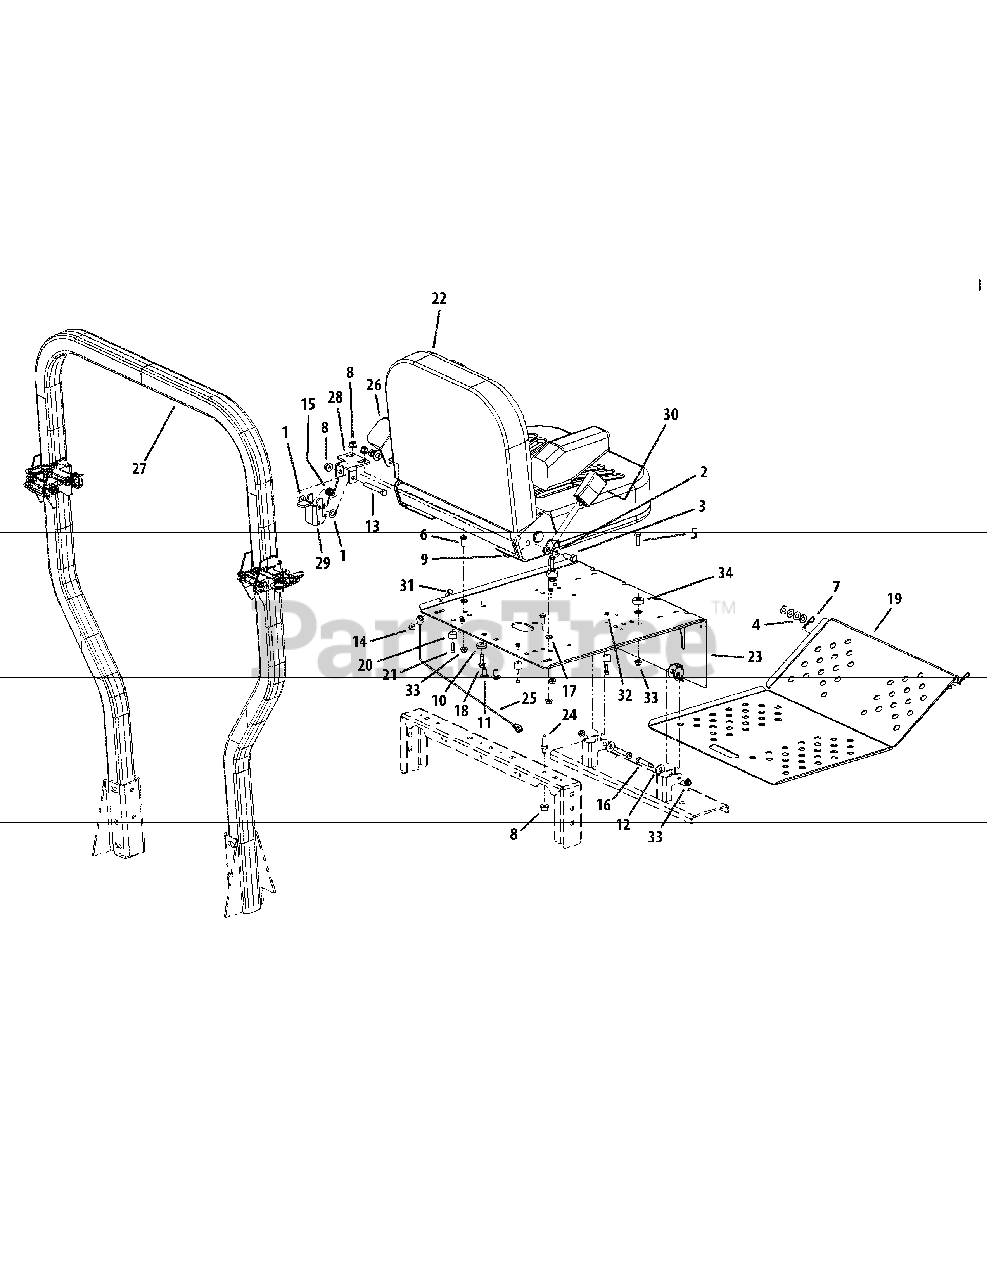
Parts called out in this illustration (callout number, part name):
1	Flat Washer, 3/8 Nylon
2	Flat Washer, 3/8
3	Hex Cap Screw, 7/16-14 x 1.00
4	Washer
5	Hex Head Capscrew, 5/16-18 x 1.00
6	Hex Head Capscrew, 5/16-18 x .75
7	Hair Pin, 3/8-1/2
8	Flange Lock, Hex Nut, 3/8-16
9	Nylock Nut, 7/16-14
10	Washer, .390 ID x 1.0 OD x .180
11	Carriage Bolt, 3/8-16 x .75 Long
12	Flat Washer, .406 ID, 1.0 OD, .105
13	Hex Cap Screw 3/8-16 x 2.75
14	Lock Nut, 1/4-20
15	Deck Lift Spring, Left Hand
16	Shoulder Bolt, .375 x 1.50
17	Push Retainer, 5/16
18	Self Tapping Screw 5/16-18 x 1.00
19	Floor Panel Assembly
20	Rubber Stop with Washer
21	Standard Cap Screw, #10-24 x .75
22	Seat includes:
23	Seat Plate Assembly
24	Adjustable Stud
25	Cable Support
27	Foldable Rops Assembly includes:
28	Seat Latch Bracket
29	Seat Latch
30	Seatbelt Buckle
31	Screw, Hex, Cap, 1/4-20 x .75
32	Nut, #10-24, Nylon Lock
33	Nut, 5/16-18, Flangelock
34	Spacer .406 ID x 1.0 OD
